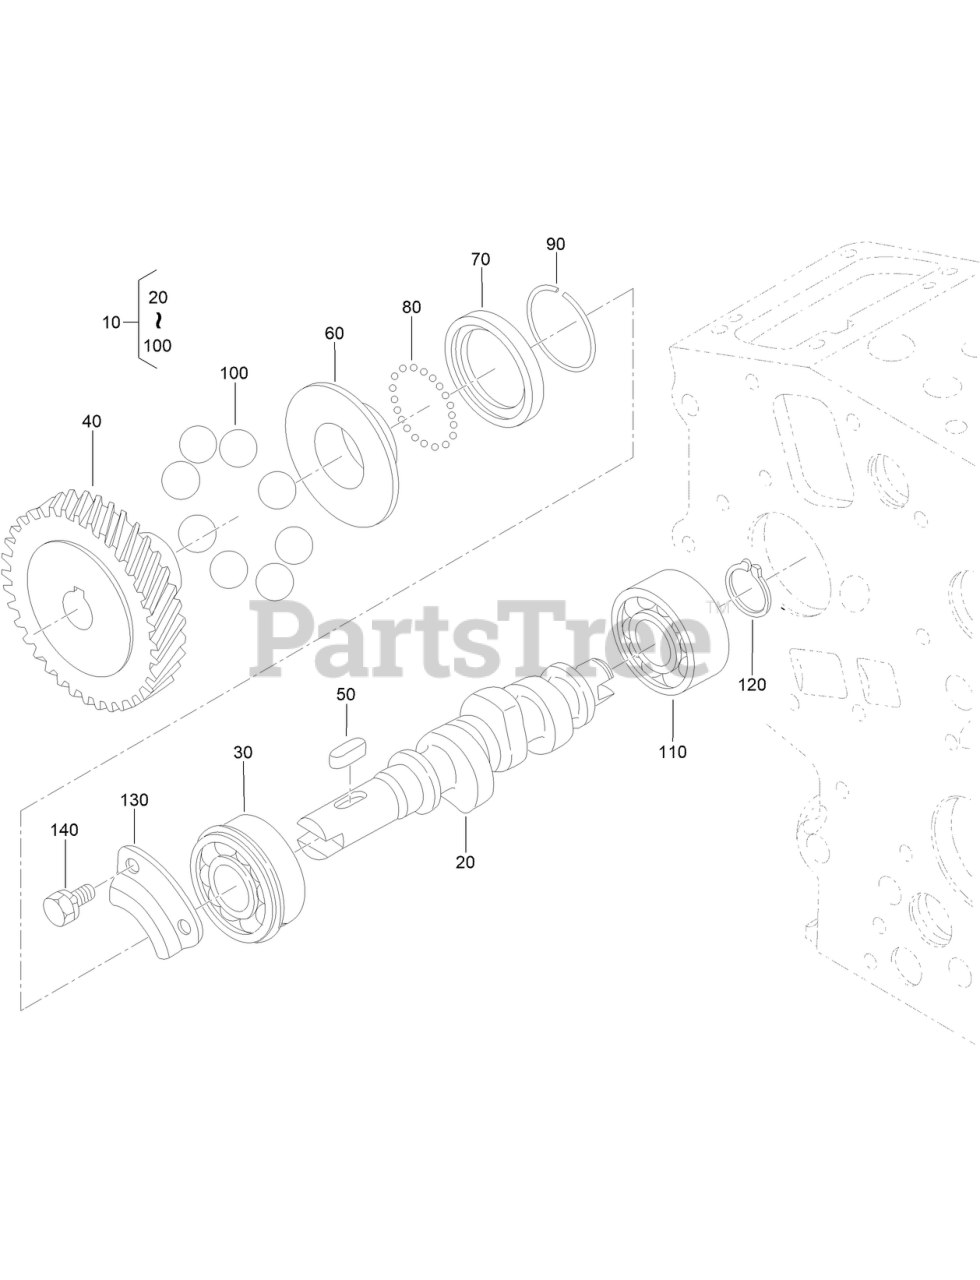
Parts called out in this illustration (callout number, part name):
10	FUEL CAMSHAFT ASM
20	CAMSHAFT-FUEL
30	BEARING-BALL
40	PUMP-GEAR, INJECTION
50	KEY-FEATHER
60	SLEEVE-GOVERNOR
70	CASE-BALL, GOVERNOR
90	CIRC-CLIP
110	BEARING-BALL
120	CIRC-CLIP, EXTERNAL
130	STOPPER-FUEL, CAMSHAFT
